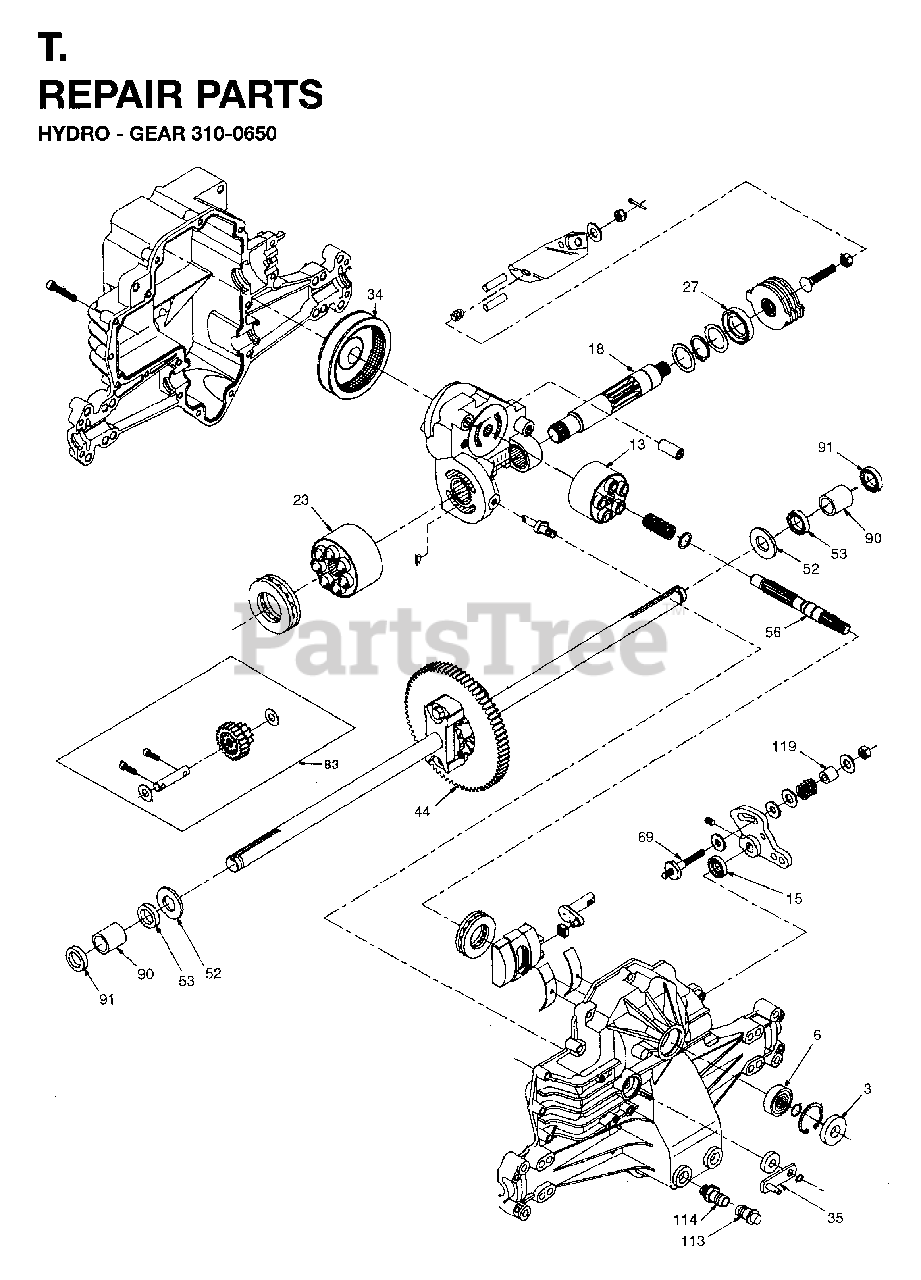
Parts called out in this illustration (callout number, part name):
6	BALL BEARING
13	BLOCK, CYL ASSY
18	SHAFT, MOTOR
23	BLOCK, CYL ASSY
34	ELEMENT, OIL FILTER
35	BYPASS ARM
44	DIFFERENTIAL ASSEMBLY
52	WASHER.HYDRO-GEAR
53	SEAL.HYDRO.45076
56	INPUT SHAFT
69	STUD 5/16-24
83	JACK SHAFT ASSY
90	SLEEVE BEARING
91	SEAL, WIPER
113	CAP, VENT ASSY
114	O-RING.ASM.70110
119	SPACER
